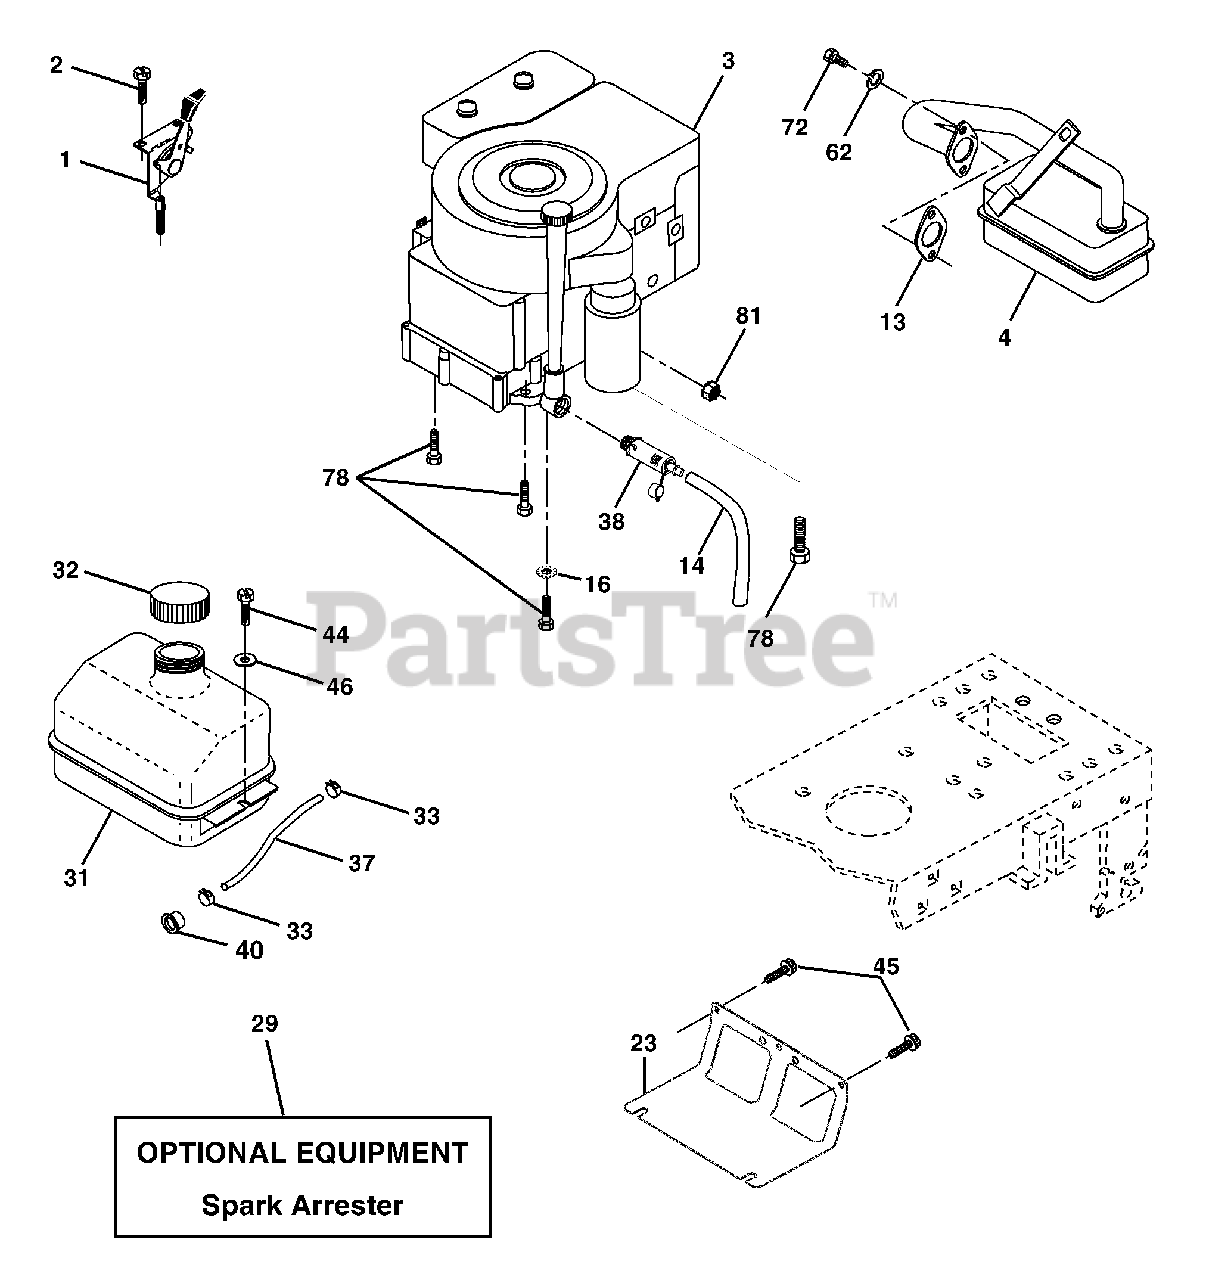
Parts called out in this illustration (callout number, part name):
1	Control Th/ch Flag
2	Screw Hex Thd Cut 1/4-20 x 1/2
4	Muffler Exhaust B&S
13	Gasket Eng 1 313 Id Tin Plated
14	Tube Drain Oil Easy
16	Washer Lock Ext Tooth 3/8
23	Shield BRN/DBR Guard
29	Kit Spark Arrestor (Flat Scrn)
31	Tank Fuel Front
32	Cap Asm Fuel
33	Clamp Hose
37	Line Fuel 20"
38	Plug Drain Oil Easy
40	Bushing Snap Nyl Blk Fuel Line
44	Screw Thdrol 1/4-20 x 3/4
45	Screw Hex Wsh Thdrol 3/8-16
46	Washer 9/32 X 7/8 X 16 Ga
62	Washer Lock Hvy Hlcl Spr
72	Screw Hexcap 5/16-18 x 3/4
78	Screw 3/8-16 x 1-1/4
81	Nut Keps Hex 1/4-20 Unc
